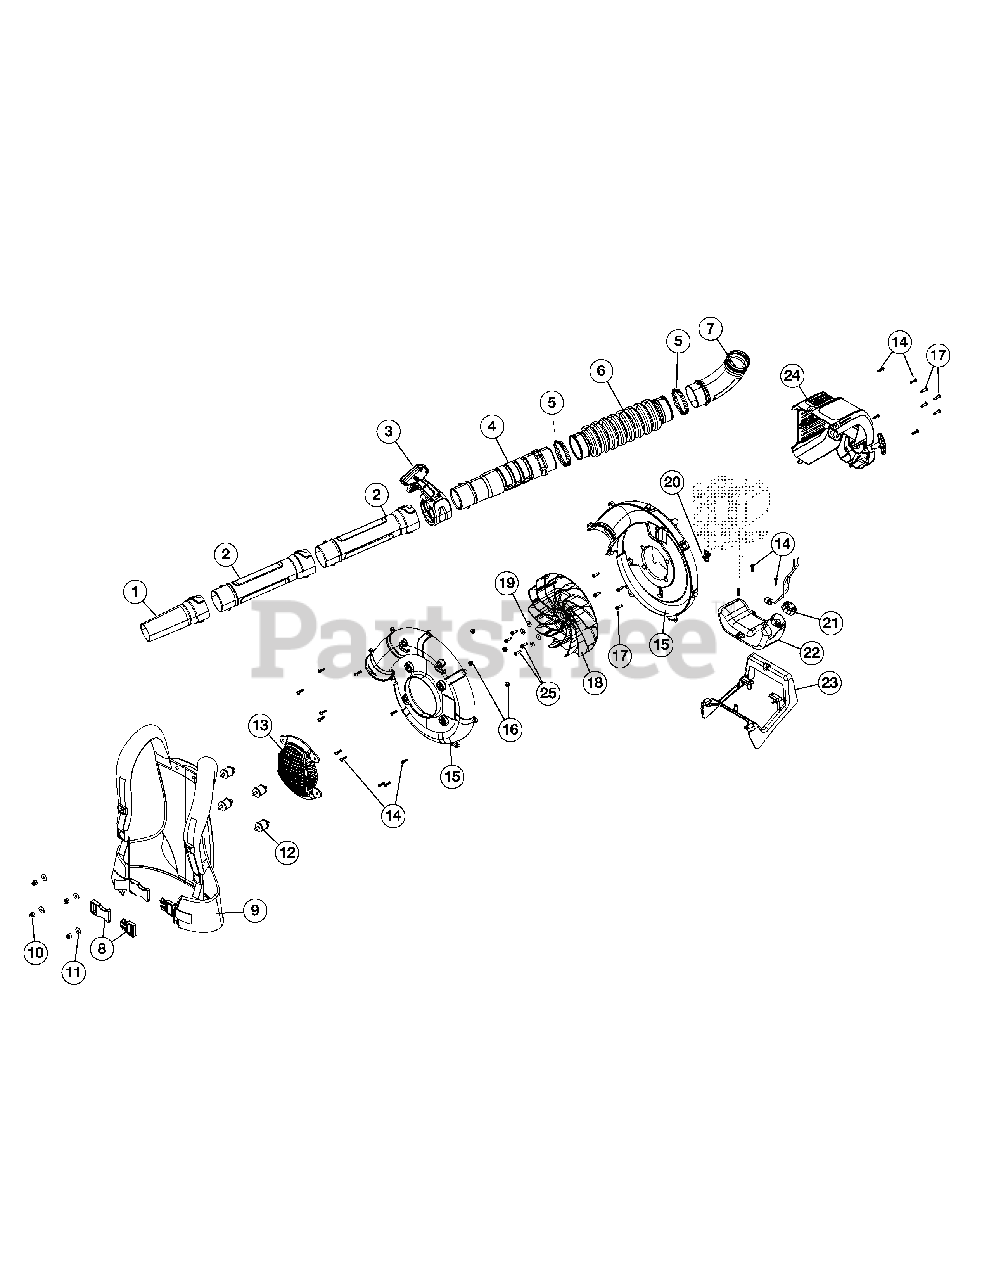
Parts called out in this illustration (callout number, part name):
2	Lower Blower Tube
3	Throttle Grip Assembly
4	Upper Blower Tube
7	Elbow Tube
8	Harness Clip
9	Harness Only
9	Hip Belt for Harness
10	Nut
12	Isolator Mount
13	Intake Cover
15	Impeller Housing Assembly
16	Nut
17	Screw
18	Impeller (Incl. Ref No. 17)
20	Throttle Retaining Clip
22	Fuel Tank Assembly (Incl. Ref No. 21)
24	Engine Cover Assembly
